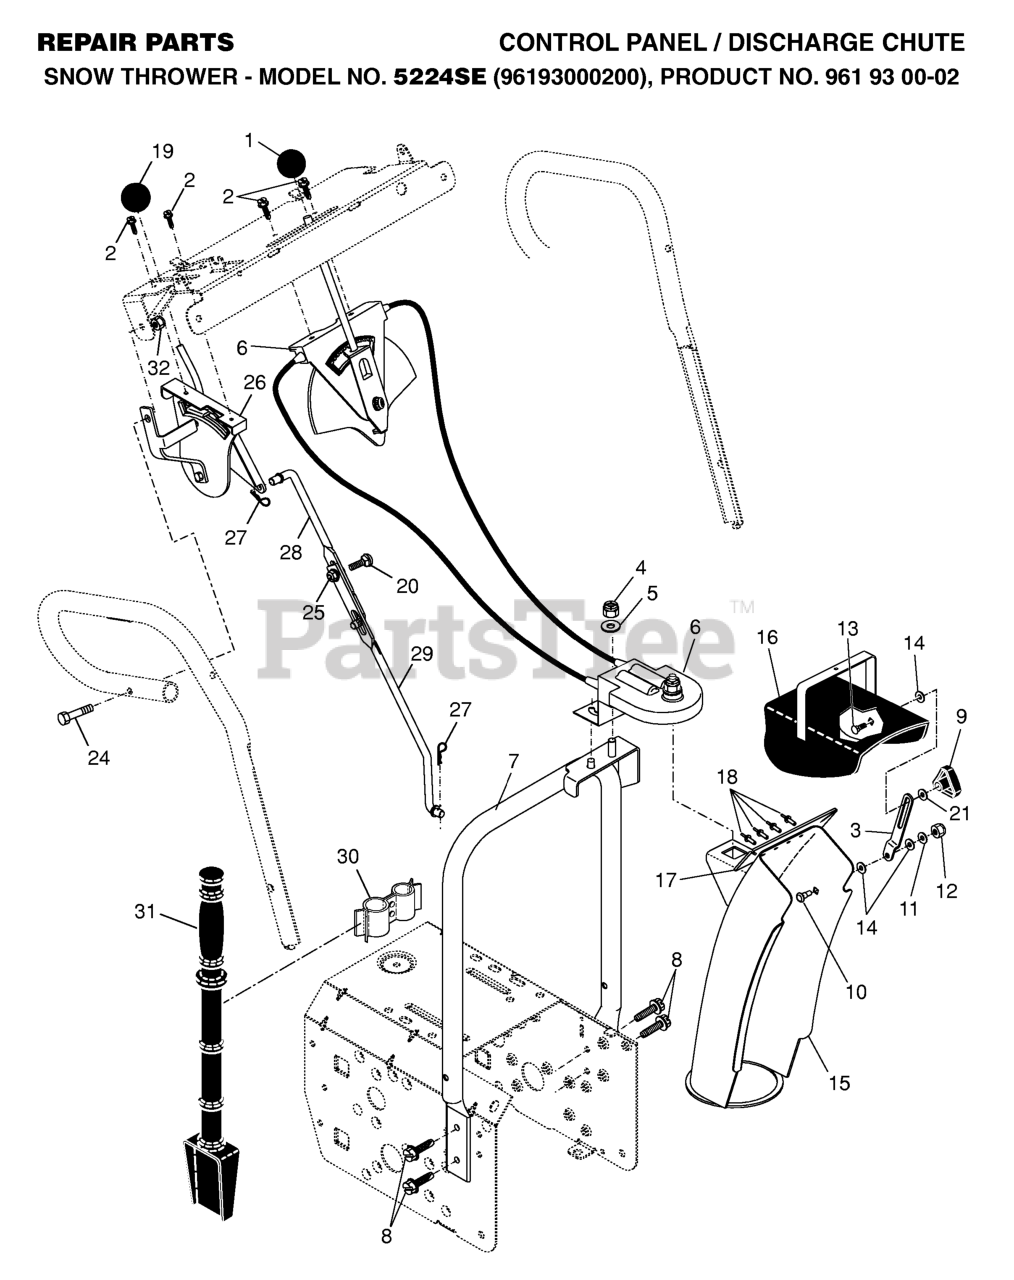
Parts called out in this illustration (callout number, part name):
1	KNOB, LEVER
2	SCREW #10-24 X 5/8
3	STRAP, CHUTE
4	NUT
5	WASHER
6	CONTROL ASSY, CHUTE ROTATER
7	SUPPORT CHUTE ROTATER
8	SELF-TAPPING SCREW 5/16-18X3/4
9	KNOB.SKID.PLATE
10	SHOULDER BOLT
11	WASHER
12	LOCKNUT.NYLOC.1/4-20
13	BOLT
14	WASHER, NYLON FRICTION
15	CHUTE ASSY
16	DEFLECTOR.WELDMENT.PNT.ORANGE
17	SEAL, DEFLECTOR
18	RIVET BLIND
19	RP KNOB, SPEED CONTROL LEVER
20	BOLT
21	WASHER.20X8.5
25	NUT.FLANGE.5/16
26	HEAD ASSY SPEED
27	SPRING RETAINER
28	ROD, UPPER SPEED CONTROL
29	ROD, LOWER SPEED CONTROL.SNOW
30	CLAMP.ASM.CLEANOUT.TOOL.SNOW
31	CLEAN OUT TOOL
32	NUT.71038.31-18.HEX.NYLOCK
